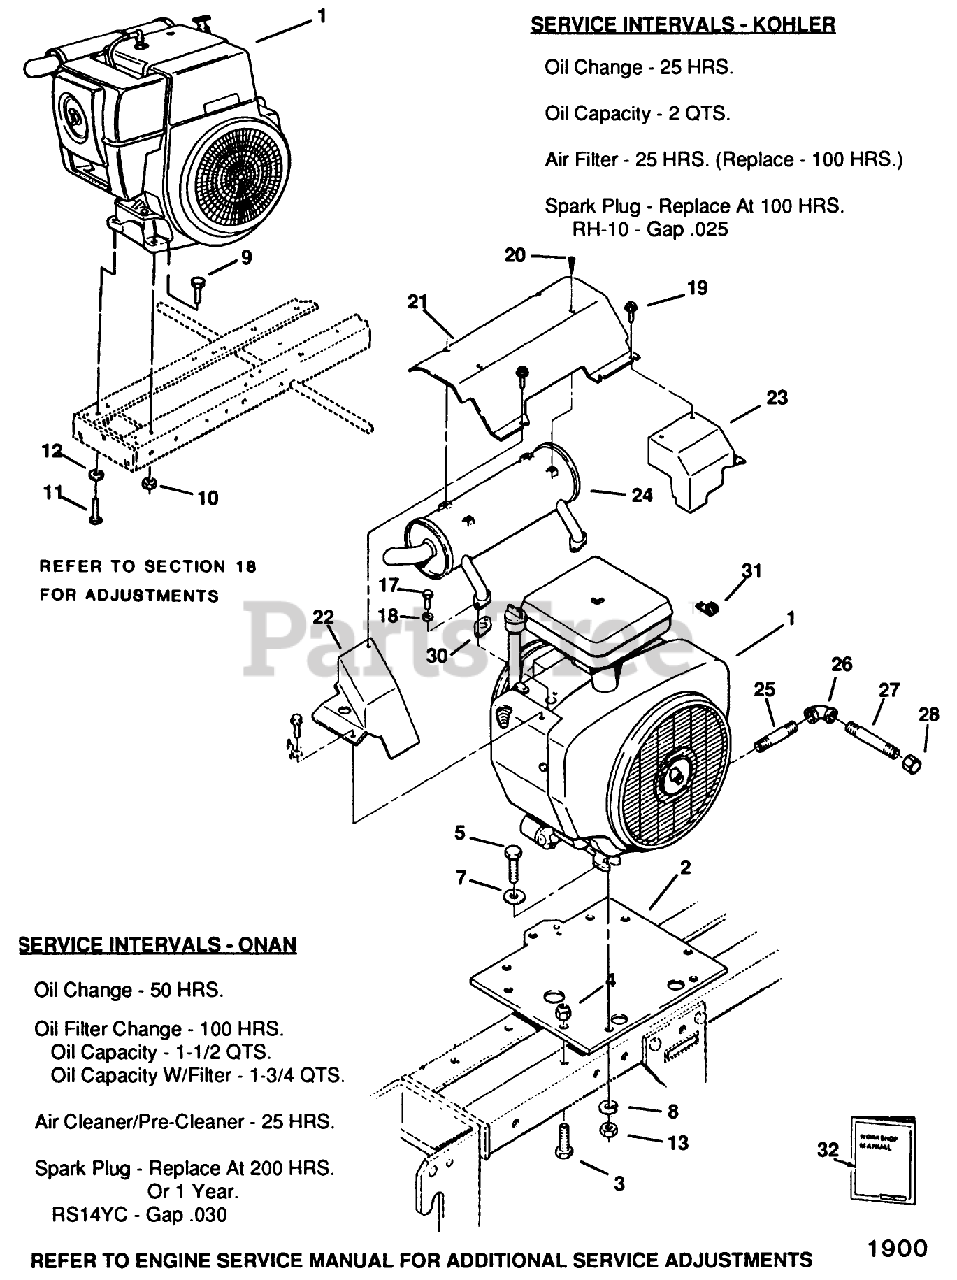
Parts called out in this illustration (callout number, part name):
1	Engine 10HP Kohler M-10-S Spec 461521 (s/n 1919902923 up)-310
2	PLATE-ENGINE *B
26	ELBOW 3/8 90 DEG
27	PIPE-NIPPLE 3/8 X 4"
31	J-CLIP
32	Magnum Kohler Service Repair Manual
